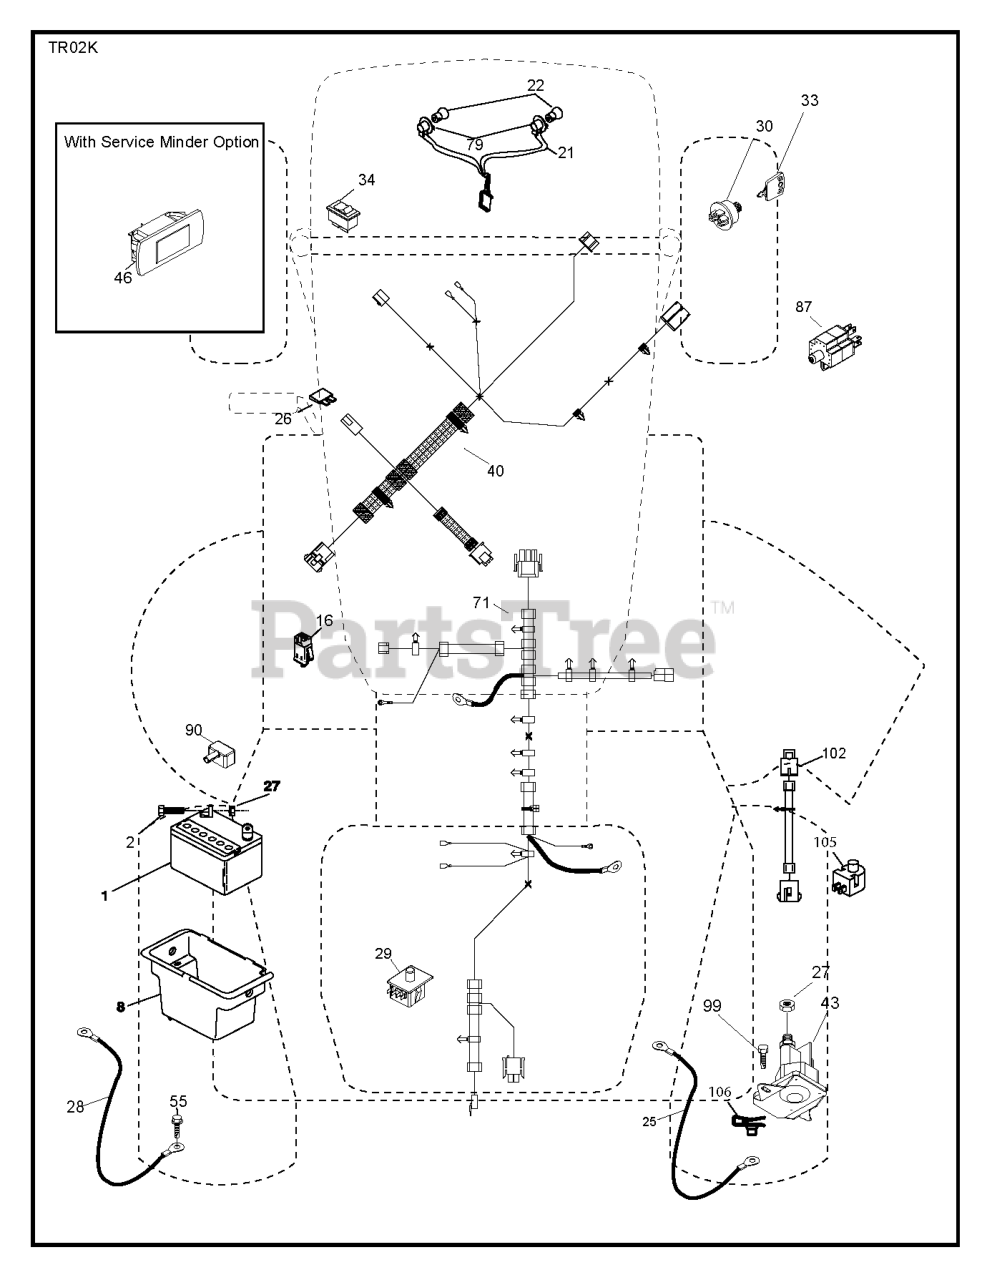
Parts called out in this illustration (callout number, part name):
1	Battery, Dry 30 Amp
2	BOLT.HEX.1/4.X.3/4.DICHROMATE
8	BOX.BATTERY.MNT.REAR.L
16	SWITCH INTERLOOK PUSH-IN
21	HARNESS.LIGHT W/4152J BULBS
25	CABLE.STARTER.6G.BL/RED.17.5
26	FUSE 20AMP
27	NUT
28	CABLE.BLACK.18"REAR.BA
29	SWITCH.SEAT.DELTA.OPC.
30	SWITCH.IGN.DELTA.W.LGH.ROS
33	KEY.CHAIN.BLISTER.PACK.GEN.USA
40	HARNESS IGN. DASH
41	SCREW
42	TERMINAL COVER
43	SOLENOID.W/BRASS.PLUNGER
46	RP.GUAGE.SRVCMNDR.HRMTR.
55	SCREW 5/16"
71	HARNESS.IGN.CHASS.TEX.REAR.BAT
79	BULB HOLDER ASM.
87	SWITCH.INTRLCK.CLUTCH.
90	COVER.TERMINAL.BATTERY
102	HARNESS PIGTAIL PCH TEX ROS
105	REVERSE SWITCH
